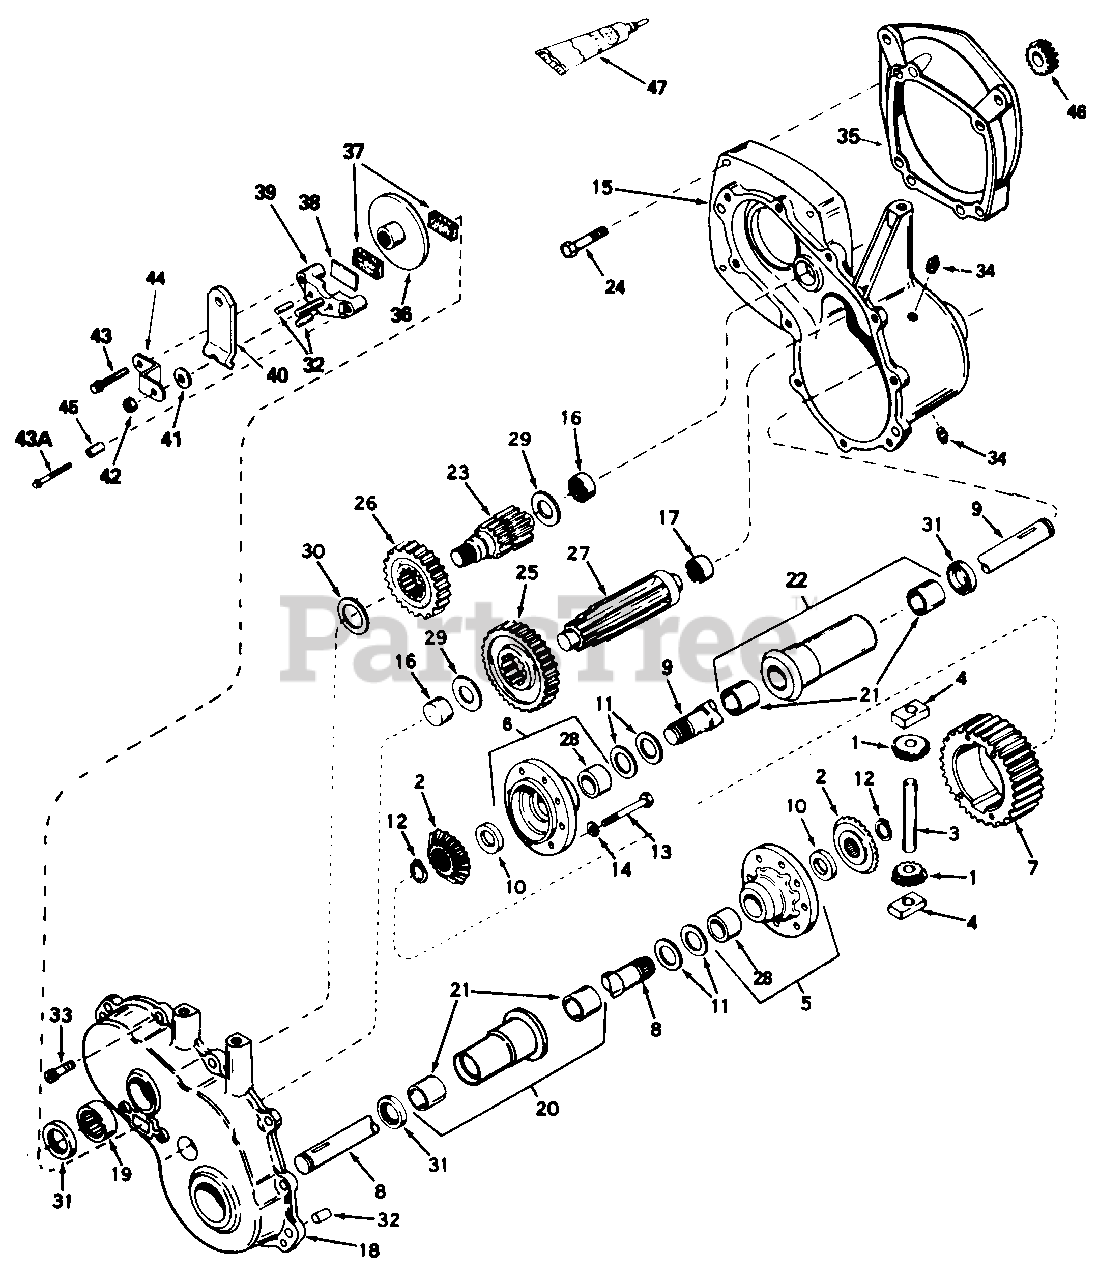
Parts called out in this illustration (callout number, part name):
1	Pinion, Bevel
2	Gear, Bevel
3	Pin, Drive
4	Block, Drive
5	Carrier Ass'y., Differential
6	Carrier Ass'y., Differential
7	Gear, Ring
8	Axle (13-1/16" Long)
9	Axle (19-1/8" Long)
10	Washer
11	Washer, Thrust
12	Ring, Snap
13	Screw, Hex Hd., 1/4-20 X 21/4
14	Lock Washer, 1/4"
15	Case Ass'y.
16	Bearing, Needle
17	Bearing, Needle
18	Cover Ass'y.
19	Bearing, Needle
20	Housing & Bushing Ass'y. (6-5/8" Long)
21	Bushing
22	Housing & Bushing Ass'y. (12-45/64" Long)
23	Shaft, Brake
24	Screw, Hex Hd., 3/8-16 x 2
25	Gear, Output
26	Gear, Idler
27	Shaft, Output
28	Bushing
29	Washer
30	Washer
31	Seal, Oil
32	Pin, Dowel
33	Screw, Hex Washer Hd. Thread Forming, 1/4-20 x 1
34	Plug, Pipe
35	Plate, Adapter
36	Disc, Brake
37	Pad, Brake
38	Plate, Brake Pad
39	Holder, Brake Pad
40	Lever, Brake
41	Washer, Flat
42	Lock Nut, 5/16-24
43	Screw, Flanged Hex Hd. Thread Forming, 1/4-20 x 1-1/4
43A	Screw, Flanged Hex Hd. Thread Forming, 1/4-20 x 2-1/4
44	Bracket
45	Spacer
46	Gear, Spur (18 Teeth)
47	Gasket Eliminator
